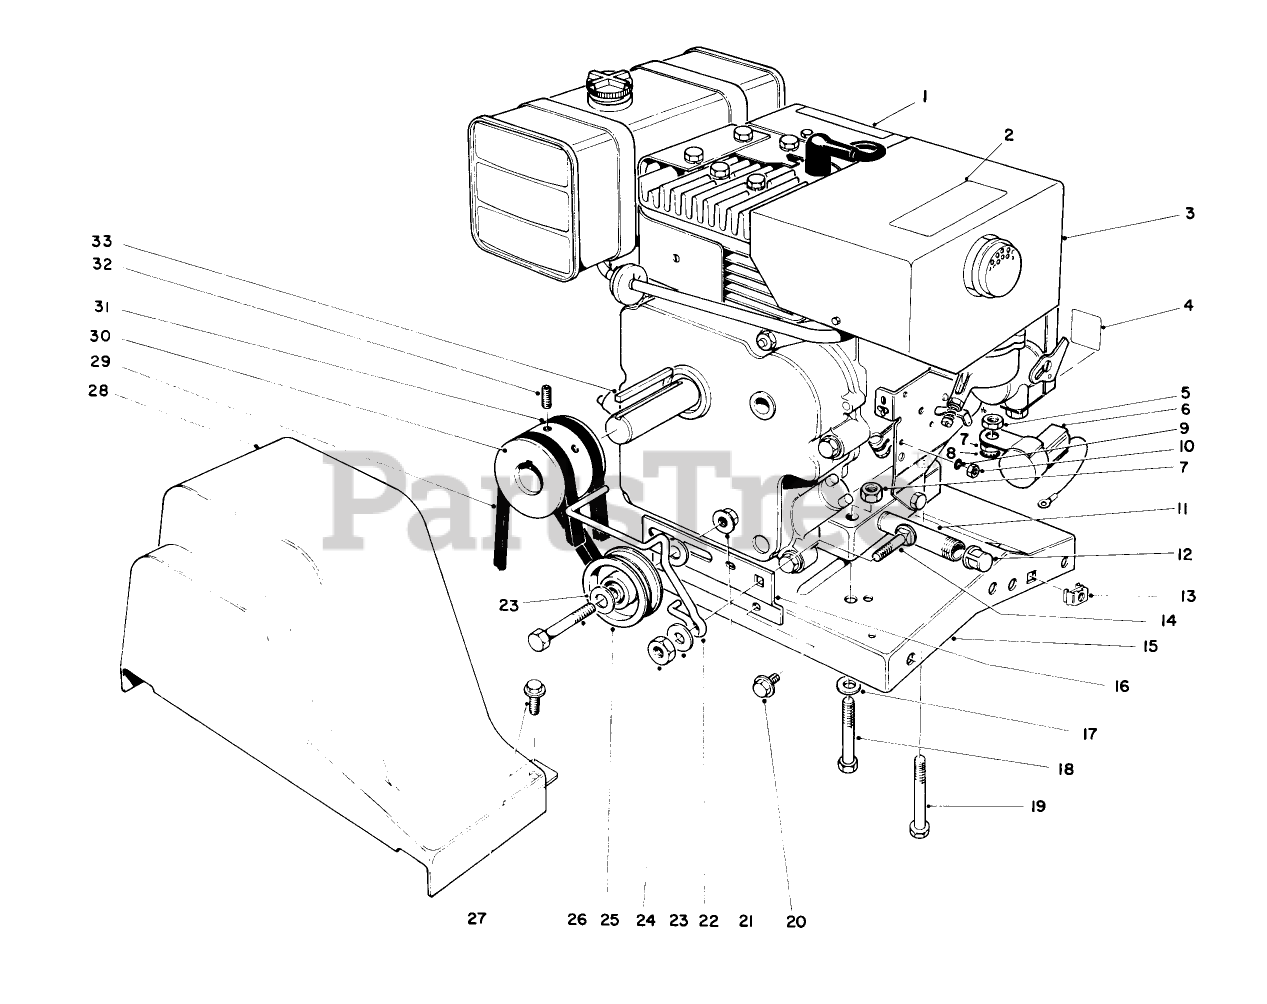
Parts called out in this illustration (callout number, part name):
1	Decal-Hazard
2	Decal Hot Surface Warning
3	Engine
4	CHOKE DECAL
5	NUT-HEX, SIDE DEFORM
6	INTERLOCK MODULE
7	NUT-LOCK, NI
8	WASHER-LOCK, INTERNAL
9	WASHER-LOCK/INT
10	NUT-LOCK
11	NIPPLE-PIPE
12	CAP-PIPE
13	RETAINER NUT
14	SCREW-CARR
15	Base-Engine
16	BELT IDLER BRKT
17	WASHER-PLAIN
18	SCREW-HH
19	SCREW-HH
20	SCREW-HHFTF
21	NUT-HHF, WHIZ
22	BELT GUIDE
23	WASHER-FLAT
24	NUT-LOCK, NI
25	PULLEY B
26	SCREW-HH
27	SCREW-HWH
28	BELT GUARD
29	V-BELT
30	Pulley
31	V-BELT
32	Screw-Set
